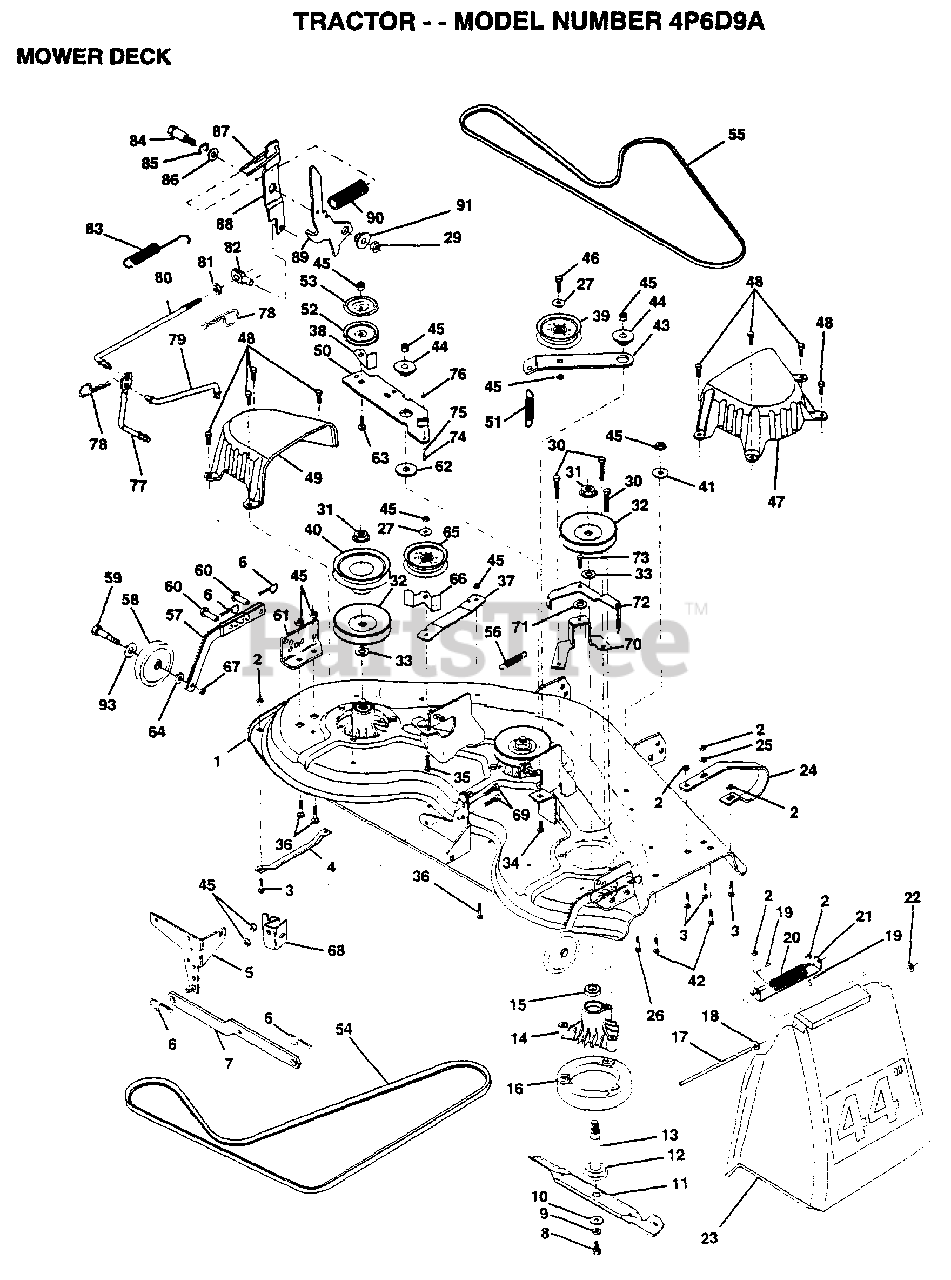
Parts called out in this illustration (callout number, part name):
1	"DECK ASM WELD44"""
4	RUNNER-LH M
5	BRKT.ASM.SW.44/50
8	BLADE BOLT
10	WASHER.HARD.BLADE
11	"BLADE.44"" HIPERF"
12	BEARING.BALL
13	SHAFT.ASM.W/BRNG
14	HOUSING.MAND.44.V
15	BEARING
16	STRIPPER RND MWR
17	ROD-HINGE T
18	WASHER
19	CAP-SLEEVE LT
20	SPRING TORSION
21	BRKT DEFLECTOR
22	NUT PUSH M
23	DEFLECTOR SHIELD
24	RUNNER.RH
25	WASHER M
26	BOLT
27	WASHER
33	WASHER
34	BOLT.3/8-14X1.25
35	BOLT
36	BOLT D
37	STIFFENER.ARM.IDL
38	KEEPER BELT IDLER
39	FLAT IDLER PULLEY
40	"PULLEY.DRIVEN.44"""
42	BOLT
43	"ARM.IDLER.SEC.44"""
44	SPACER RETAINER
47	"COVER.MAND.RH.44"""
48	SCREW.1/4-20X5/8
49	COVER.MANDREL.LH
50	ARM.IDLER.PRIMARY
51	"SPRING.SEC.44""VEN"
52	PULLEY.IDLER.VGRO
53	SHIELD.IDLER.44.V
54	BELT-V MOWER PRIM
55	BELT-V.88.12.MW
56	"SPRING,EXTENTION"
57	BAR.ASM.GUAGE.WHL
58	WHEEL.GAGE.BLK.PL
59	BOLT M
60	PIN.CLEVIS
61	BRACKET.GUAGE.WHL
62	HARDENED WASHER
63	BOLT.3/8-16X1.50
64	WASHER
65	IDLER-FLAT T
67	LOCKNUT
68	BRACKET PVT MCH
70	"BRACKET SUPT 44"""
71	HARD SMALL WASHER
72	ARM BRAKE ASM
73	BOLT.SHLD.5/16-18
75	SHOULDER BOLT
76	LOCKNUT
77	PIVOT ROD
78	RETAINER M
79	ROD CLUTCH SECON
80	ROD.CLUTCH.PRIM44
81	NUT
82	TRUNION ADJ
83	SPRING.EXT.RETURN
84	SHOULDER BOLT
85	RING
86	WASHER
87	SPRING KEEPER
88	CLUTCH ARM SECOND
91	BUSHING
93	WASHER
